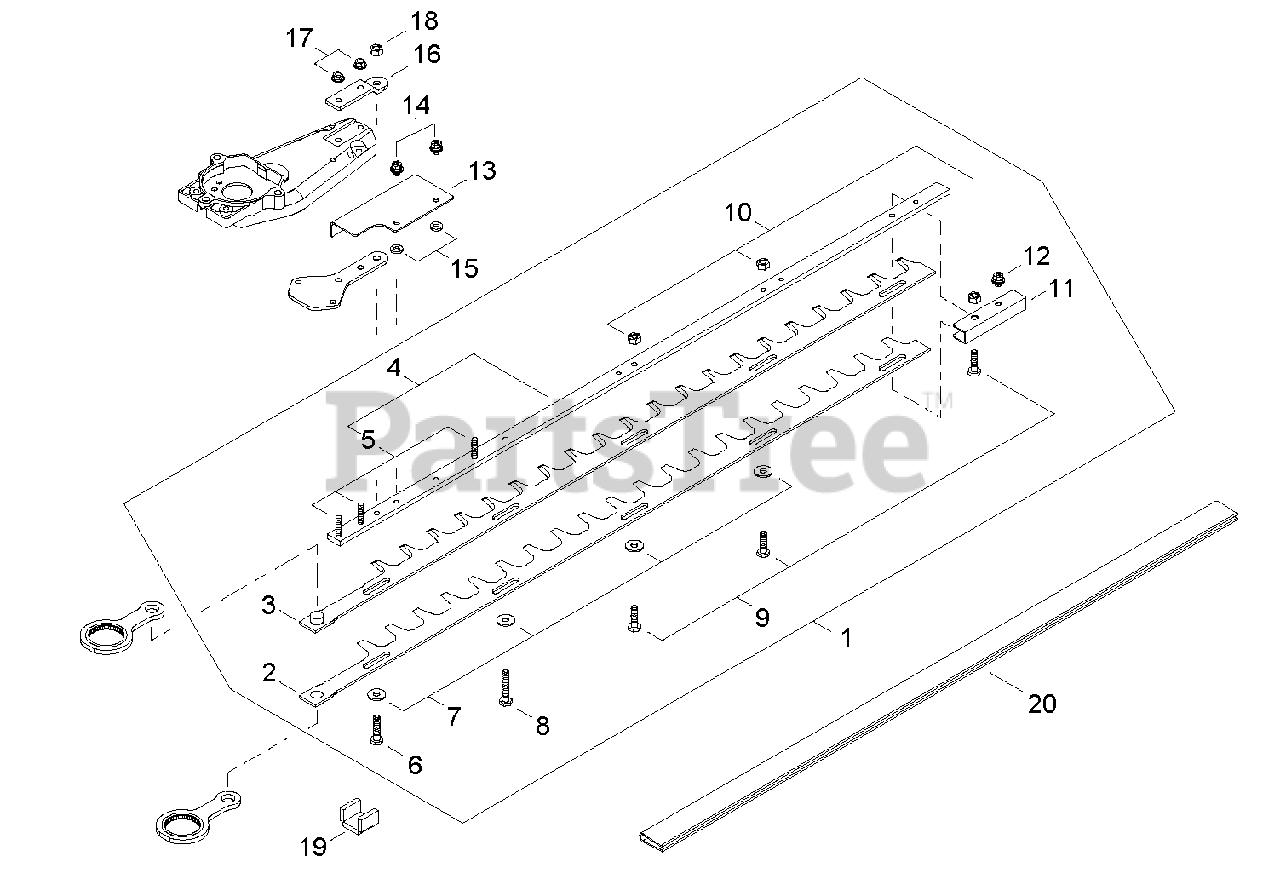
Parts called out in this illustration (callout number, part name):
1	CUTTER ASSY, 30"
2	BLADE, 30" CHROME LOWER
3	BLADE, 30" CHROME UPPER
4	GUIDE BAR ASSY, 30"
5	SCREW 5×25 SUS
7	WASHER M6
8	BOLT M6×32
9	BOLT M6×20
11	PLATE, GUIDE
12	BOLT M5×8
13	PROTECTOR
14	BOLT M5×8
15	WASHER 5
16	BRACKET, CUTTER
17	NUT, FLANGE M5
19	PACKING, FELT
20	SCABBARD 30"
